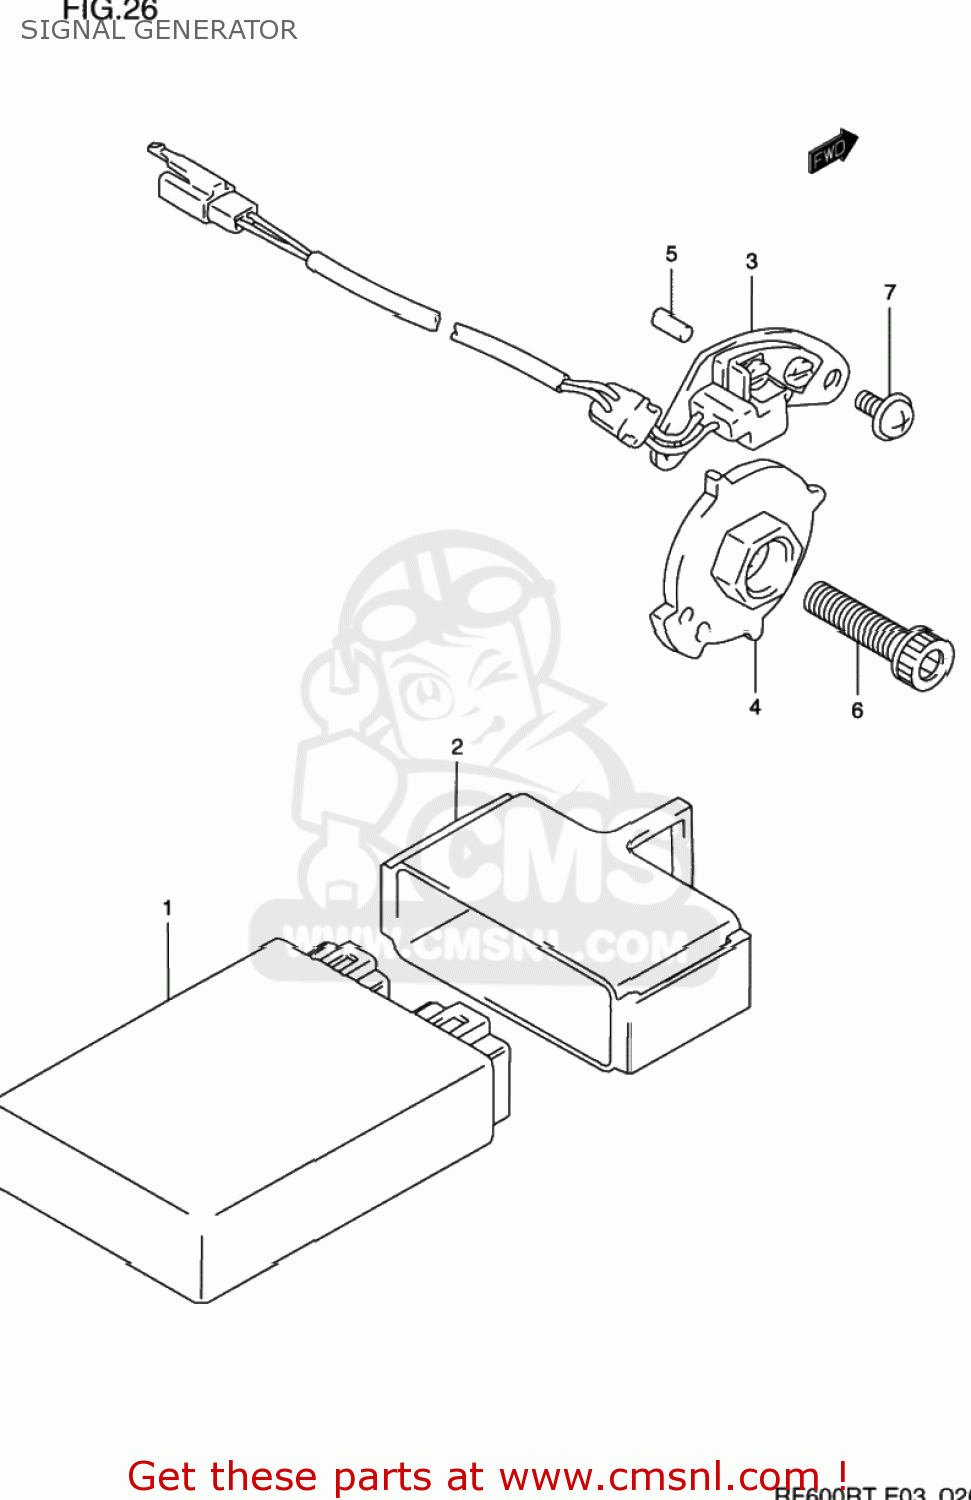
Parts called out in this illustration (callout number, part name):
1	IGNITER
2	CUSHION,IGNITOR
3	STARTER,SIGNAL GENERATOR
4	ROTOR,SIGNAL GENERATOR
5	PIN
6	BOLT
7	SCREW
